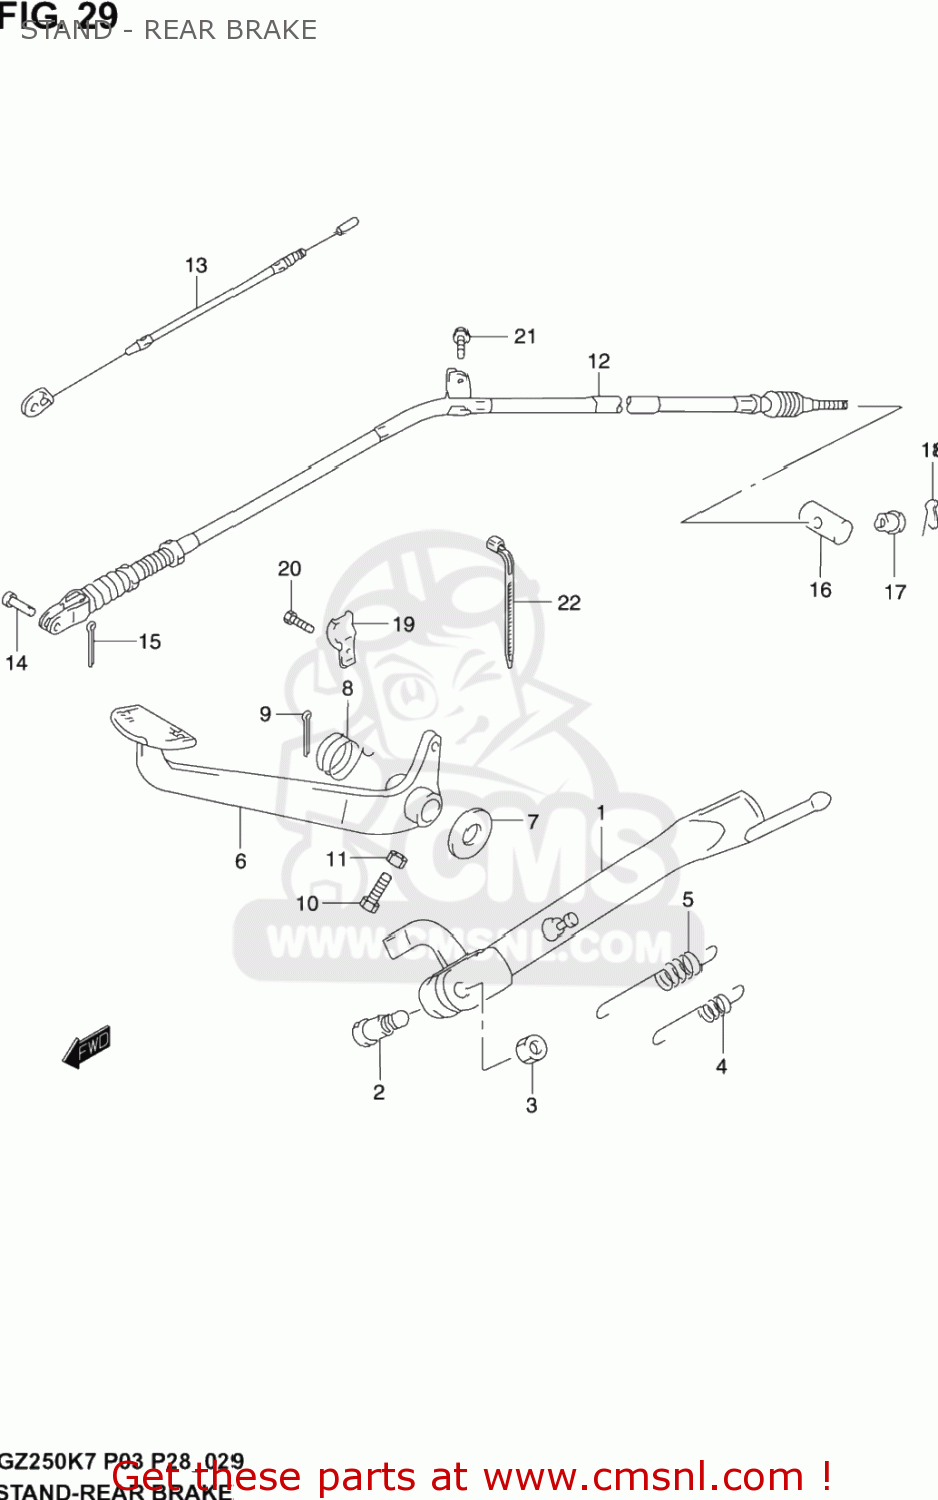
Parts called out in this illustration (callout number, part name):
1	STAND,PROP
2	BOLT(10X34)
3	NUT
4	SPRING
5	SPRING
6	PEDAL, BRAKE
7	WASHER(16.5X22X1)
8	SPRING
9	PIN
10	BOLT
11	NUT
12	CABLE,RR BRAKE
13	CABLE,STOP LAMP SWITCH
14	PIN(L:17.5)
15	PIN
16	PIN
17	NUT
18	CLIP
19	GUIDE,RR BRAKE CABLE
20	BOLT
21	BOLT
22	CLAMP(L:145)
